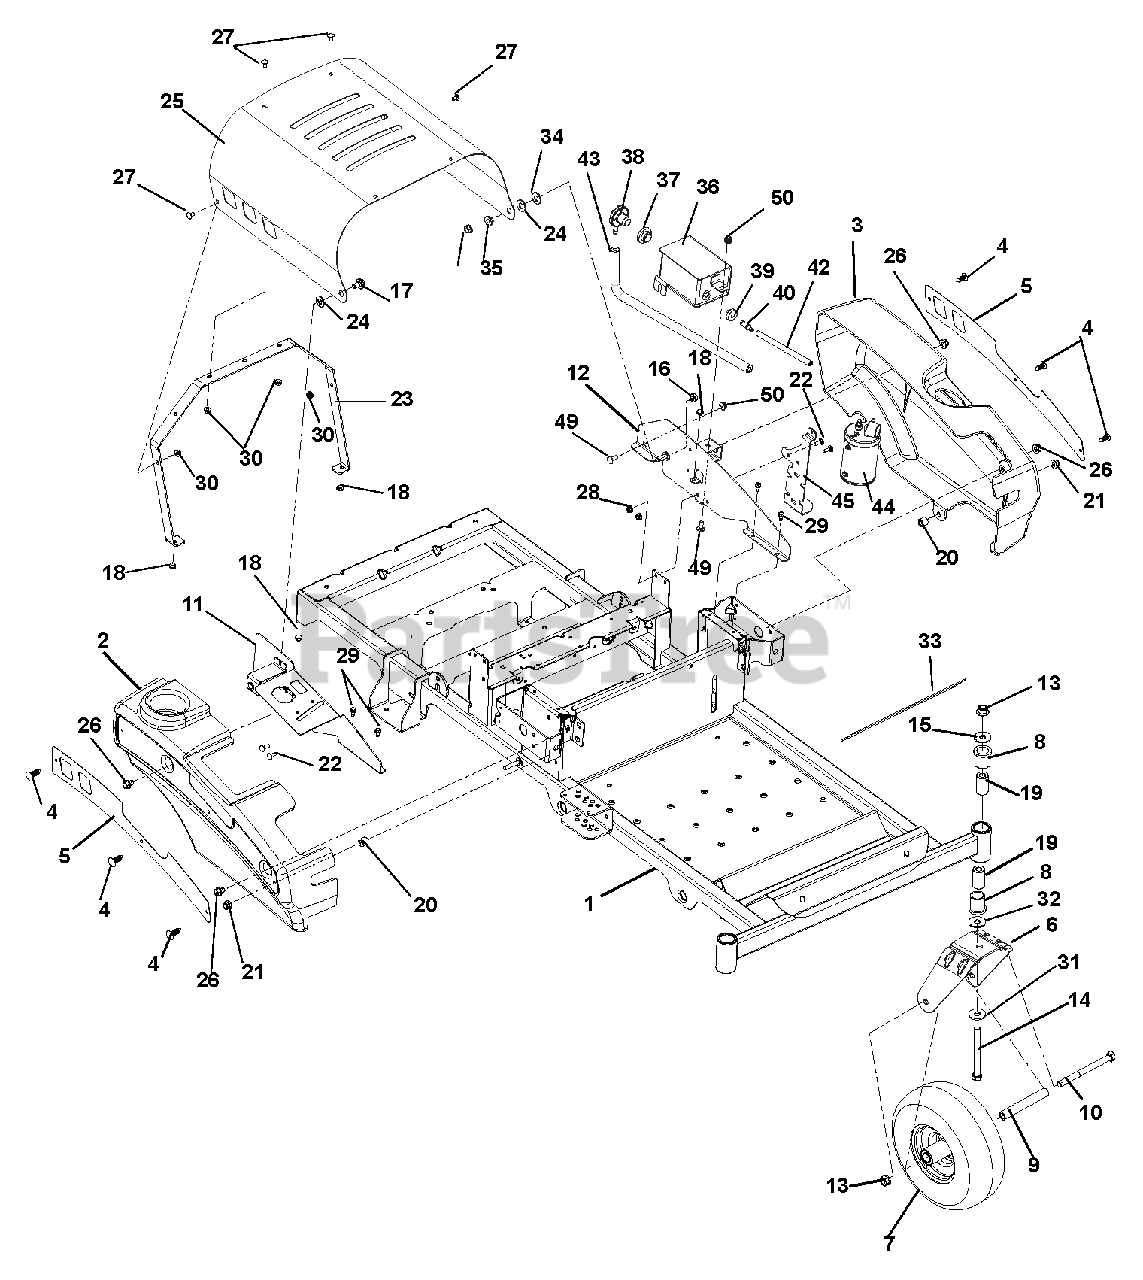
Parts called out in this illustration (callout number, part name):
1	WMT, BBZ FRAME
2	FENDER, RH
3	FENDER, LH
4	RIVET, .25 NYLON PANEL
5	PLATE, FENDER
6	CASTER FORK
7	TIRE/WHL ASM, FRONT
8	BSHG-FLG 1.00X1.25X1.50X1.50
9	SPACER, ROLLED WHEEL
10	@BLT-HEX .50-13X6.50 GR5 YWZC
11	WLDMNT, LH FENDER MOUNT
12	WMT, FENDER MOUNT LH
13	@NUT-LK-TOP-FLG .50-13 YWZC
14	@BLT-HEX .50-13X5.00 GR5 YWZC
15	WSHR-FL-STL.511X1.441X.125 YWZ
16	@NUT-LK-TOP-FLG .38-16 YWZC
17	BOLT-SHLDR .375-16X.150
18	BUMPER GROMMET
19	SPACER, CASTER .50X1.00X1.84
20	BSHG-SLV .391X.688X.52 PM
21	@NUT-LK-NYL-FLG .38-16 YWZC
22	@BLT-RDHDSQNK .25-20X.75 G5YZ
23	BRACE, BBZ HOOD
24	WSHR-FL-NYL .518X1.000X.080
25	HOOD, ZOOM
26	@SCR-TAP .38-16X.50 HWH TR YWZ
27	@BLT-RDHDSQNK .25-20X.50 G5YZ
28	@NUT-LK-NYL-FLG .25-20 YWZC
29	@SCR-TAP .25-20X.50 HWH TR YWZ
30	@NUT-LK-TOP-FLG .25-20 YWZC
31	WSHR-FL-STL .515X1.625X.250 YZ
32	WSHR-FL-STL .518X2.0X.105 YWZC
33	GRIP, ADHESIVE (1" X 16" BLK)
34	@WSHR-FL-STL.531X1.06X.095YWZC
35	BSHG-FLG .385X.500X.875X.406
36	TANK, ZOOM FUEL EXPANSION
37	GROMMET, REMOTE VENT NITRILE
38	VALVE,FUEL ROLL OVER
39	BSHG-FLG .375 X 1.062 X .625 R
40	FITTING, STRAIGHT FUEL
41	CLAMP, FUEL LINE
42	HOSE, .25 LOW-PERM BULK GAS
43	HOSE, .25 LOW-PERM BULK GAS
44	CARBON CANISTER, 300CC
45	BRKT-MOUNT, CANISTER BBZ
46	P-PLASTIC TIE STRAP LARGE
47	CLAMP-HOSE, SPRING .188
48	HOSE, .188 LOW-PERM BULK GAS
49	@BLT-RDHDSQNK .31-18X.75 G5YZ
50	@NUT-LK-TOP-FLG .31-18 YWZC
